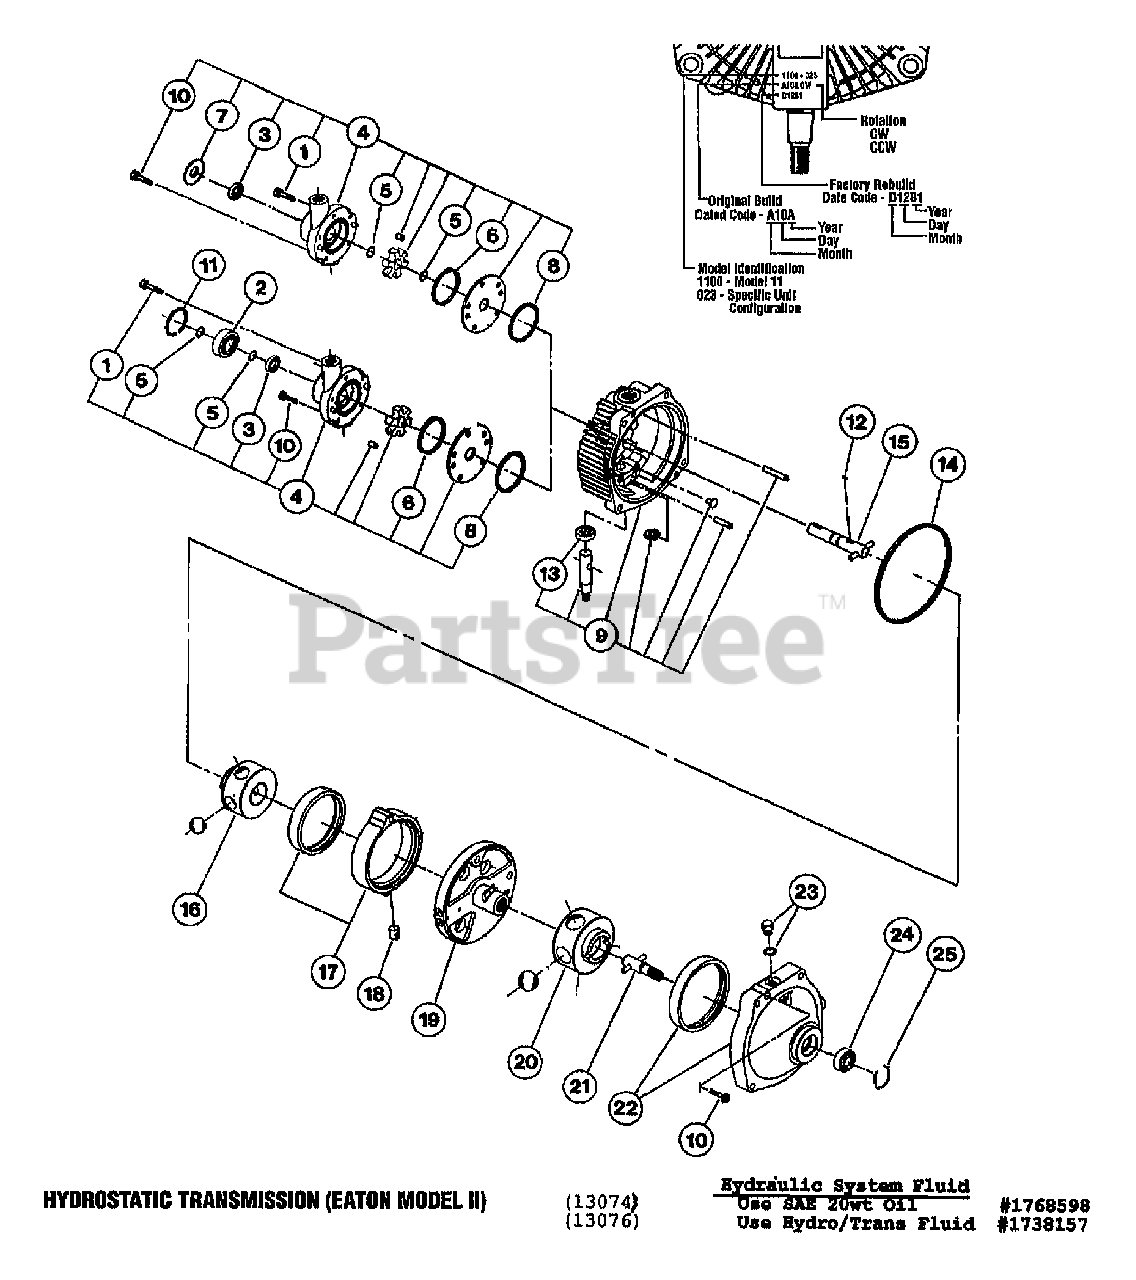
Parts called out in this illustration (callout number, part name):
1	SOCKET HEAD CAPSCREW
3	SEAL-OIL
4	KIT-PUMP CHARGE
5	RING-SNAP
6	RING-SQ SEAL
7	SHIELD-GRASS
8	RING-SQ SEAL
9	ASSM-COVER
10	SOCKET HEAD CAPSCREW
12	PIN-DRIVE
13	SEAL-OIL
14	RING-SQ SEAL
15	SHAFT-INPUT (W/KEY)
16	ASSM-PUMP ROTOR & BALL
17	ASSM-RING CAM
18	RING-CAM INSERT
19	ASSM-PINTLE
20	ASSM-MOTOR ROTOR & BALL
21	SUBASSM-OUTPUT SHAFT
22	ASSM-BODY
23	SUBASSM-O RING PLUG
24	BRG-BALL (OUTPUT)
25	RING-RETAIN
